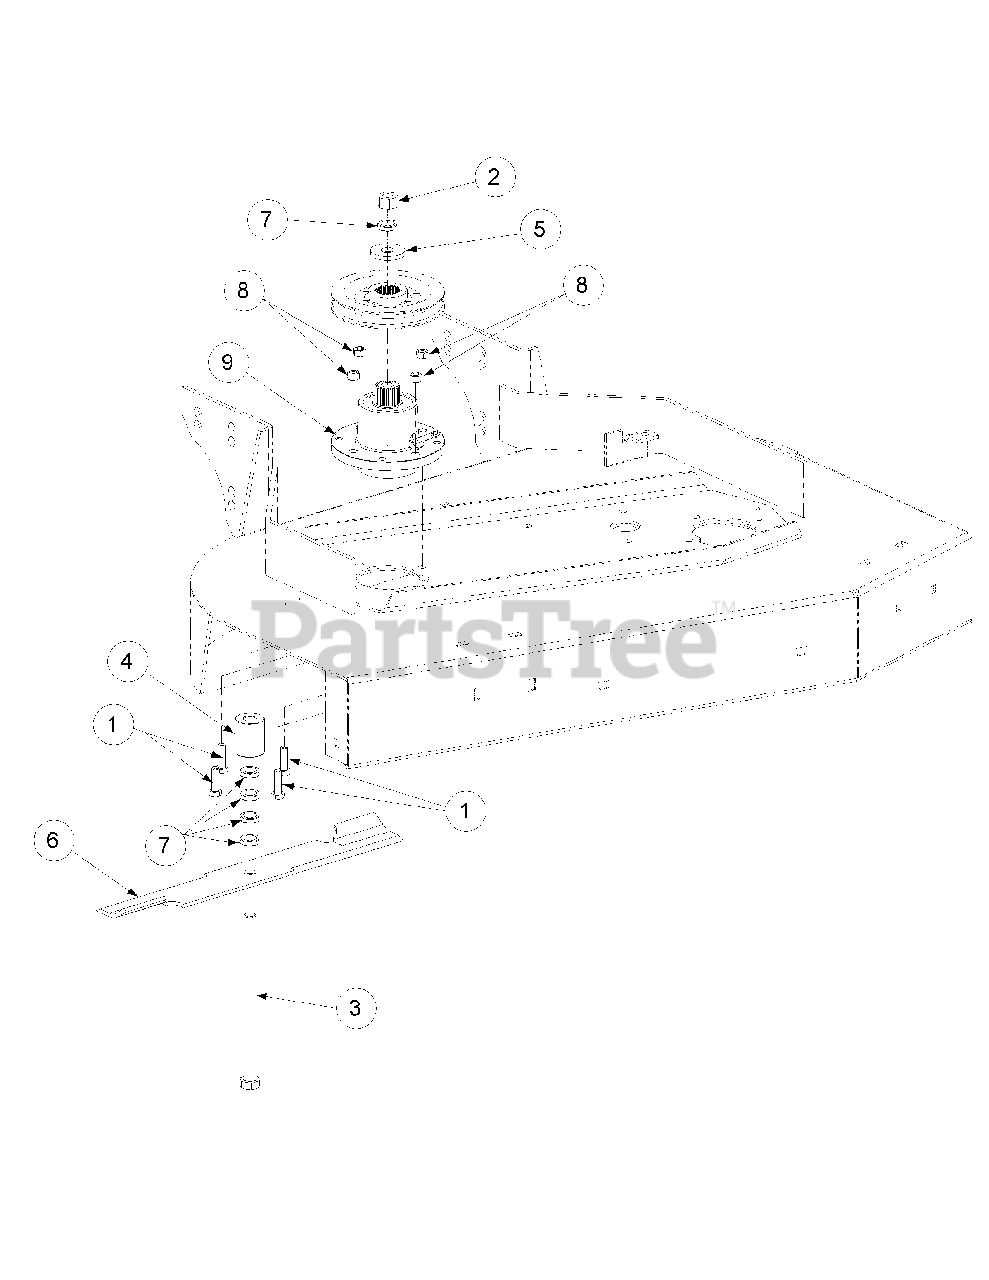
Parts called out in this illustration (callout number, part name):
1	Hex Cap Screw, 3/8-16 x 1-1/4
2	Hex Nut, 5/8-11
3	Hex Cap Screw, 5/8-11 x 9
4	Blade Spacer, .630 x 1.500 x 1.850
5	Flat Washer, .656 ID x 1.313 OD
6	18" Rotary Blade
7	Blade Spacer, 5/8 ID, 1/4 Thick
8	Hex Nut Flange Lock, 3/8-16
8	Spindle Assembly
